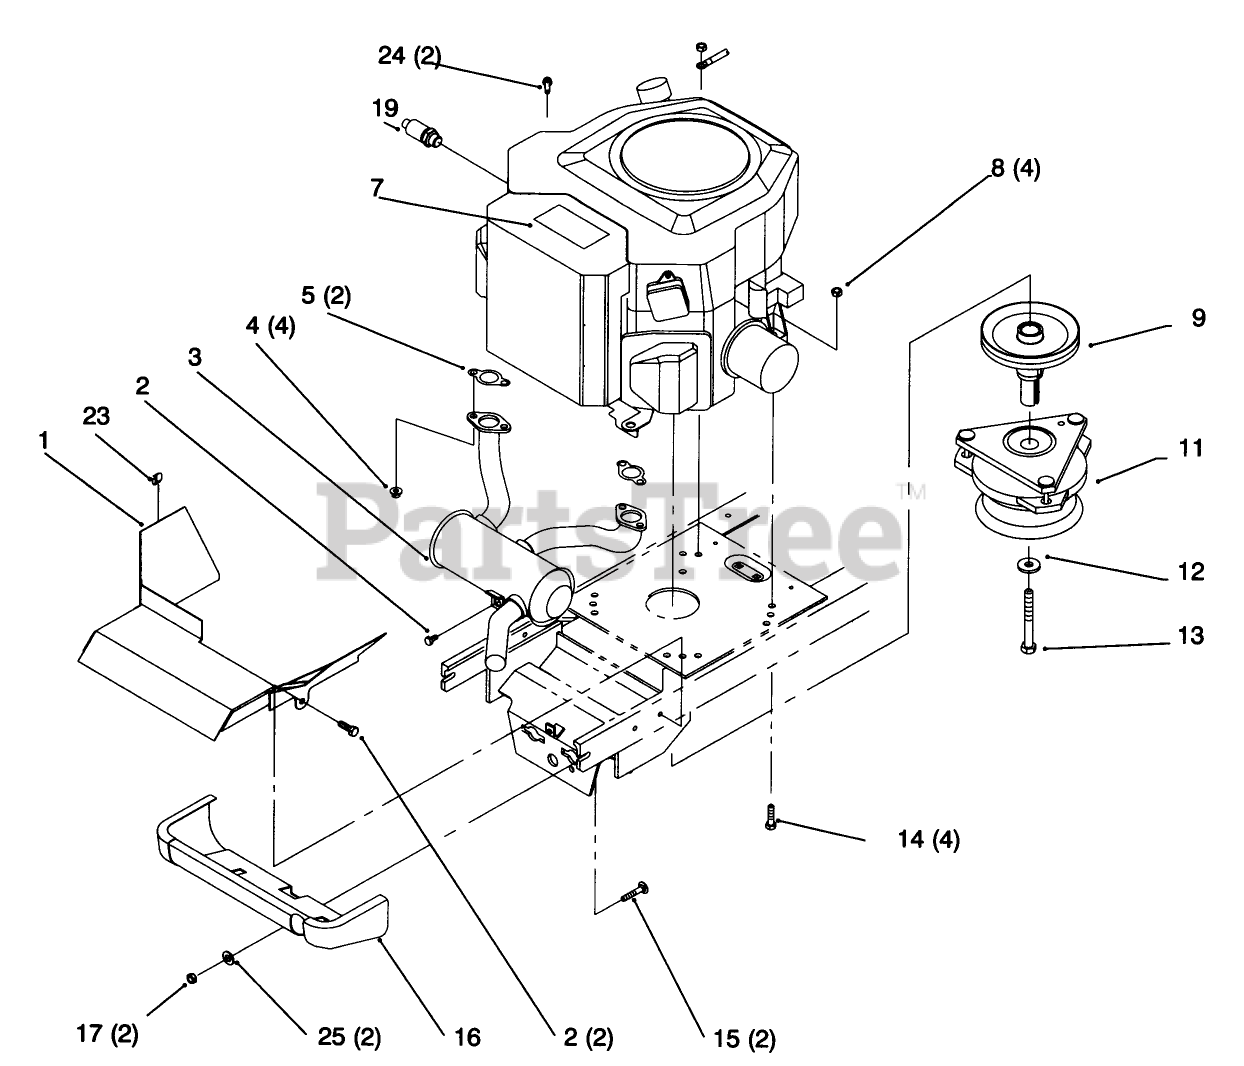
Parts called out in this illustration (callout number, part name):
2	SCREW-HWHTF
7	DECAL - ENGINE
8	NUT-LOCK, NI
9	PULLEY-ENGINE
11	CLUTCH - ELEC PTO
12	WASHER
13	SCREW-HH
14	SCREW-HH
15	SCREW-CARR
17	NUT-LOCK, NI
19	VALVE-DRAIN, OIL
23	CLIP-RETAINER, WIRE
24	SCREW-PPH
25	WASHER-FLAT
